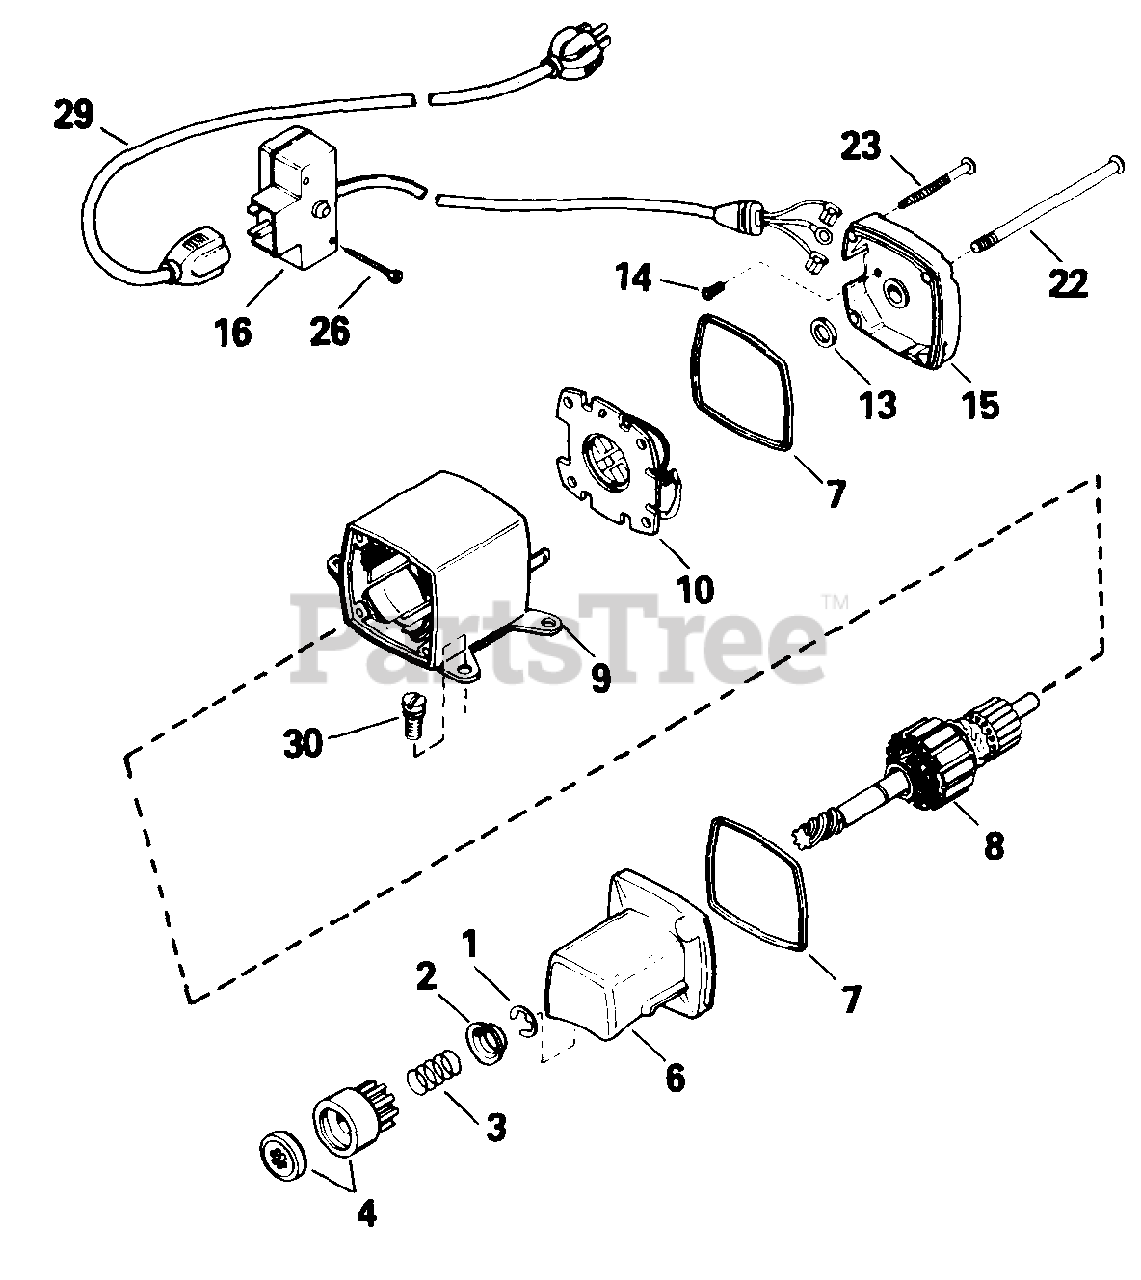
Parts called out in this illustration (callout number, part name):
1	Ring, Retainer
2	Retainer, Spring
3	Spring, Anti-Drift
4	Nut & Gear
6	Cap Ass'y., Drive End
8	Armature
9	Housing Ass'y.
10	Card Ass'y., Brush
13	Washer, Thrust
14	Screw, Ground
15	Cap Ass'y., Commutator End
16	Box Ass'y., Switch
22	Bolt, Case
23	Screw, Grounding
26	Screw, Hex Hd. Self-Tap, 6-32 x 2 1/2
29	Cord, Extension (10'6")
30	Screw, Hex Hd. Self-Tap, 1/4-20 x 11/16
